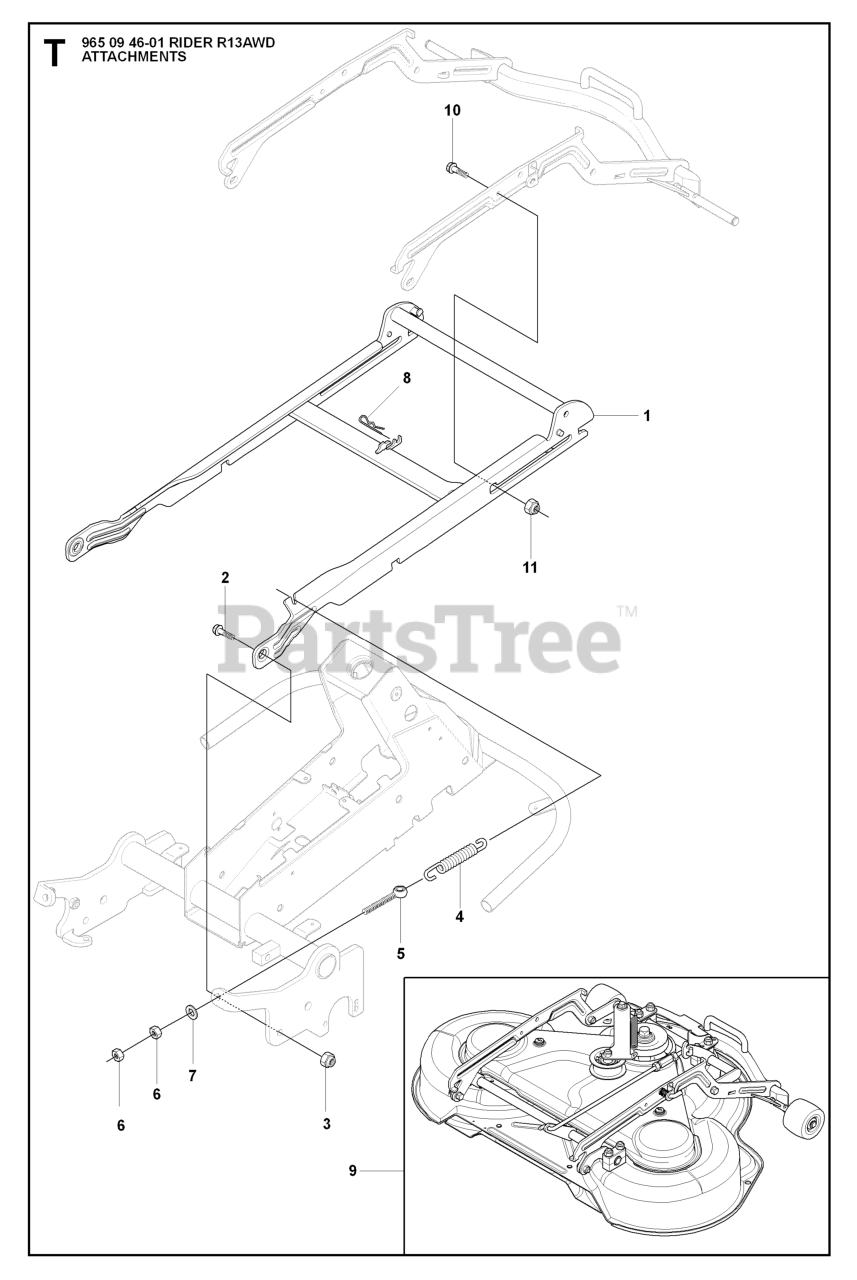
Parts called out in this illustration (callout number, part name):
6	NUT
7	WASHER
10	COLLAR SCREW
11	LOCKNUT M8
